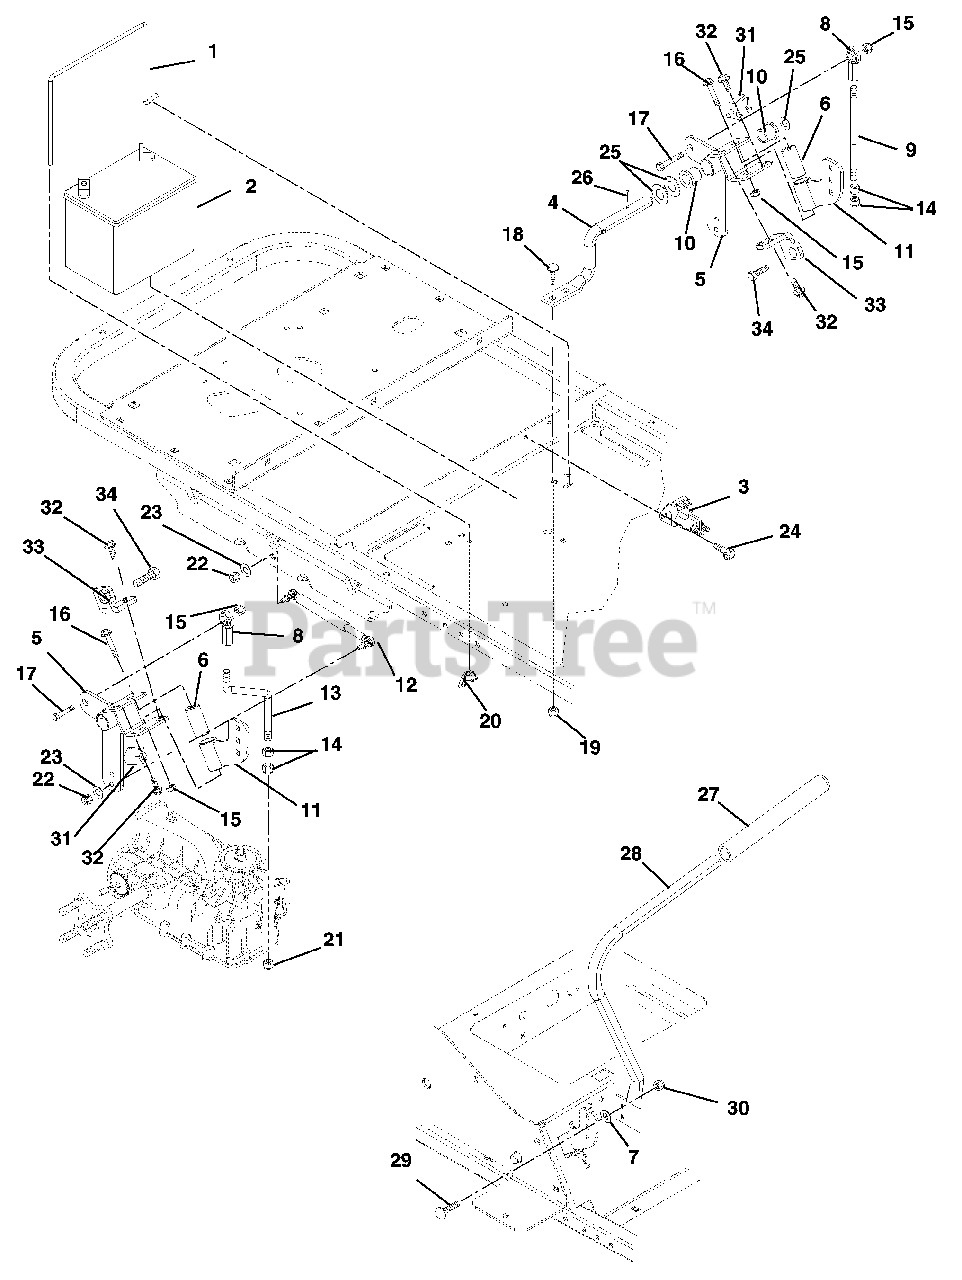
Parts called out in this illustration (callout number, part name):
1	BATTERY ROD
2	BATTERY, 300 CCA 10U1L
2	BATTERY W/ TUBE
3	SOLENOID
4	ROD PIVOT
5	WMT, CONTROL
6	BSHG, SPCR .502X.997X2.03 PM
7	@WSHR-LK-EXT.326X.599X.031YWZC
8	ROD END, 1/2 RH
9	ROD-TRANSAXLE LH
10	BUSHING-1"X.75"X1"
11	WMT, HANDLEBAR
13	ROD-TRANSAXLE RH
14	NUT-JAM .50-20 GR2 YWZC
15	@NUT-LK-TOP-FLG .50-13 YWZC
16	@BLT-HEX .50-13X3.00 GR5 YWZC
17	@BLT-HEX .50-13X1.50 GR5 YWZC
18	@BLT-RDHDSQNK .38-16X1.00 G5YZ
19	@NUT-LK-NYL-FLG .38-16 YWZC
20	NUT-LK WING .250-20 YWZC
21	NUT-LK-JAM-NYL .50-20 GR2 YWZC
22	NUT-HEX M8-1.25 YWZC
23	@WSHR-LK .31X.078 REG YWZC
24	@SCR-TAP .25-20X.37 HWH YWZ TR
25	WSHR-FL-STL .754X1.000X.032 YZ
26	PIN-ROLL .188X1.13
28	HANDLEBAR WLDM'T RH
28	HANDLEBAR WLDM'T LH
29	BLT-RDHDSQNK.31-18X.88 GR5YWZC
30	@NUT-LK-NYL-FLG .31-18 YWZC
31	SWITCH- DOUBLE POLE N.O./N.O.
32	@SCR-TAP 10-24X.50 HWH TR YWZC
33	WMT, HANDLE STOP
34	SCR-SKH .25-20X1.25 PL
